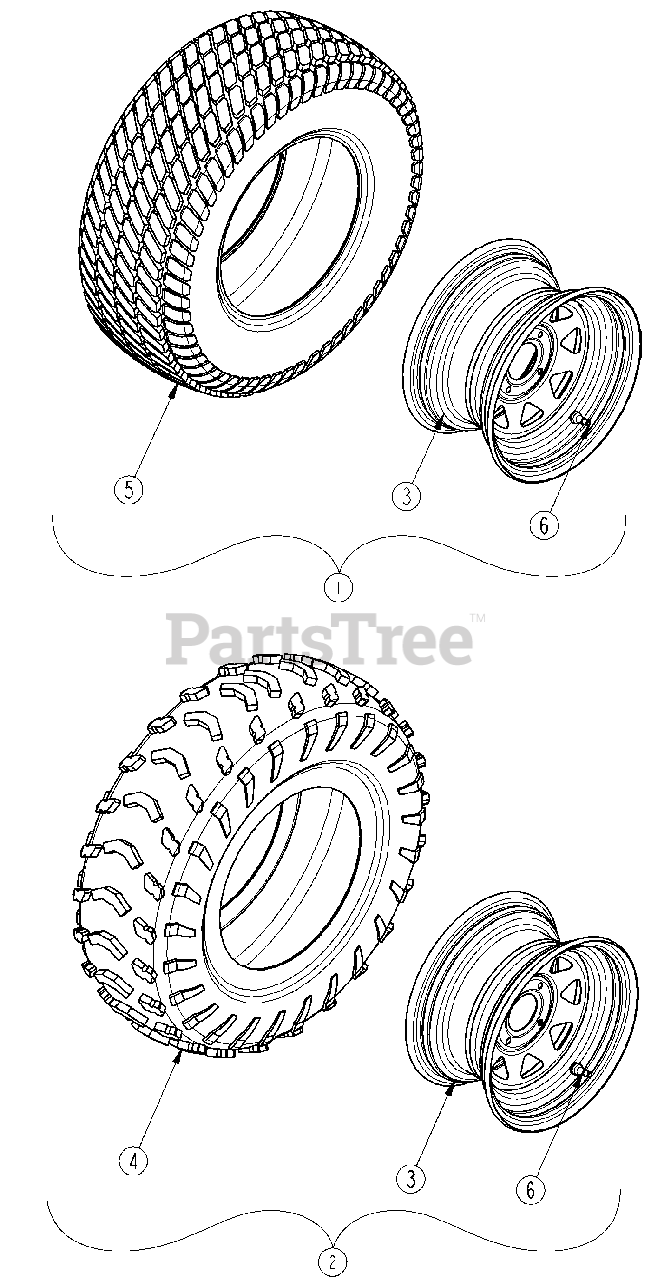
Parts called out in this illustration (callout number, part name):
1	TIRE/RIM FRONT TURF 23-8.5-12
2	AT TIRE/RIM, GRAY RIGHT FRONT
3	AT TIRE/RIM, BLACK RIGHT FRONT
4	AT TIRE/RIM, GRAY LEFT FRONT
5	AT TIRE/RIM, BLACK LEFT FRONT
6	RIM, 12X7 4-4 BOLT GRAY
